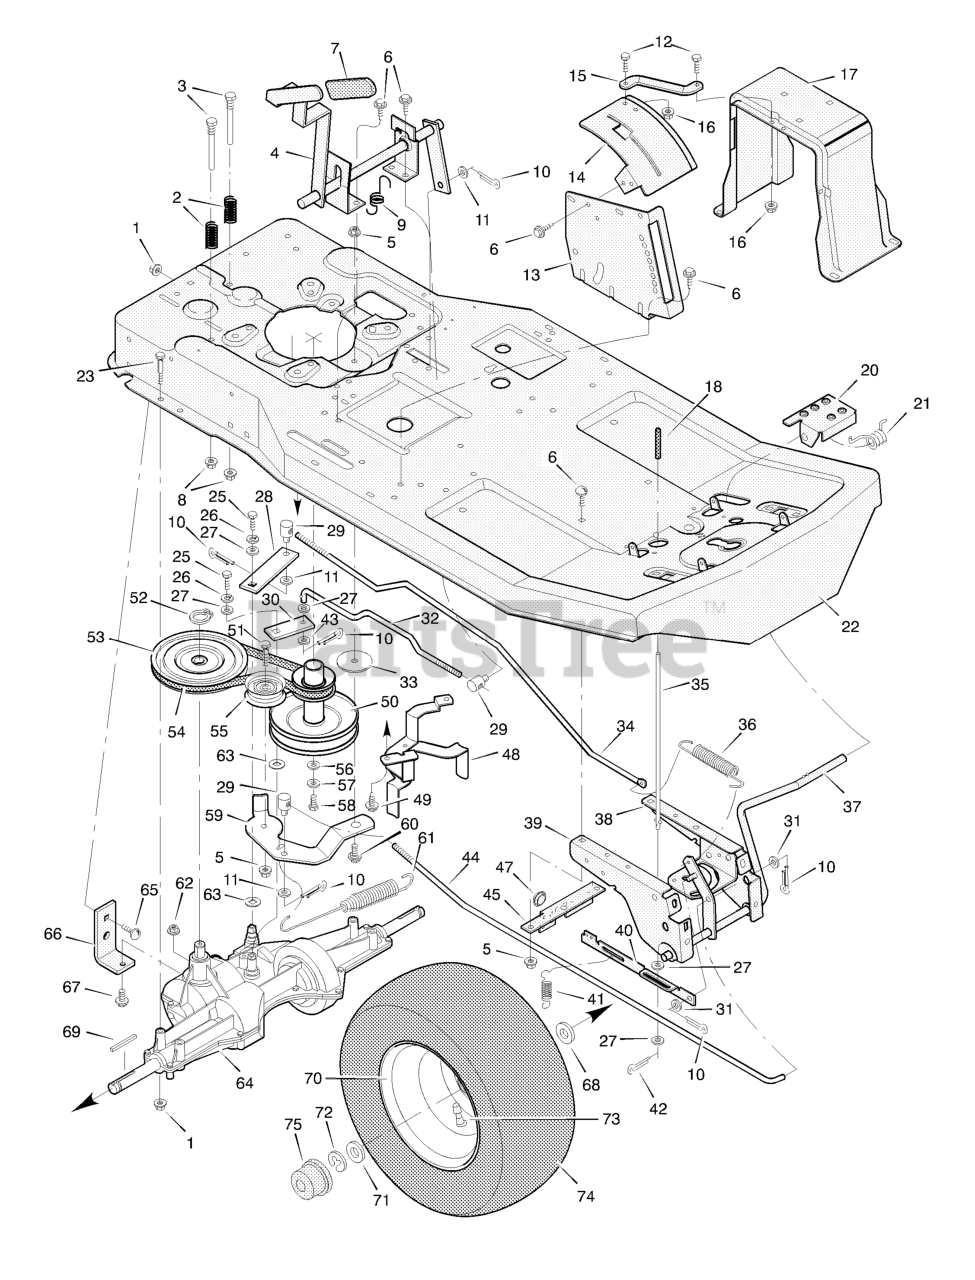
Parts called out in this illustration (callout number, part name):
1	Locknut, Flange
2	Spring, Compression
3	Guide, Belt
4	Shifter Assembly
5	Locknut, Flange
7	Grip, Shift Lever
8	Hex Nut
9	Spring, Extension
10	Pin, Cotter
12	Bolt, Hex
13	Plate, Index
14	Gate, Shift
15	Brace, Shift Gate
16	Locknut, Flange
17	Support, Seat
18	Grip, Parking Brake
21	Spring
22	Frame Assembly
23	Bolt, Hex
25	Bolt, Hex
26	Lockwasher
28	Yoke, Brake
29	Nut, Adjusting
30	Yoke, Shift
31	Washer
32	Rod, Shift
33	Washer, Hardened
34	Rod, Brake
35	Rod, Parking Brake
36	Spring, Extension
37	Lever, Pedal
38	Plate, Left Suspension
39	Plate, Right Suspension
40	Link, Parking Brake
41	Spring, Extension
42	Pin, Cotter
44	Rod, Clutch
45	Stop, Parking Brake
47	Grommet
48	Guide, Belt
50	Pulley Assembly, Stack
51	Bolt, Hex
52	Ring, Retainer
53	Pulley, Drive
54	Belt, Motion Drive
55	Pulley, Idler
57	Lockwasher
58	Bolt, Hex
59	Bracket, Idler
60	Bolt, Shoulder
61	Spring, Extension
62	Locknut, Hex
64	Transaxle, Dana Model 4450-1 **
65	Bolt, Carriage
66	Bracket, Transaxle
67	Bolt, Hex
69	Key, Square
70	Wheel & Tire Assembly
72	E--Ring
73	Valve Stem
74	Tire *
75	Hub Cap
